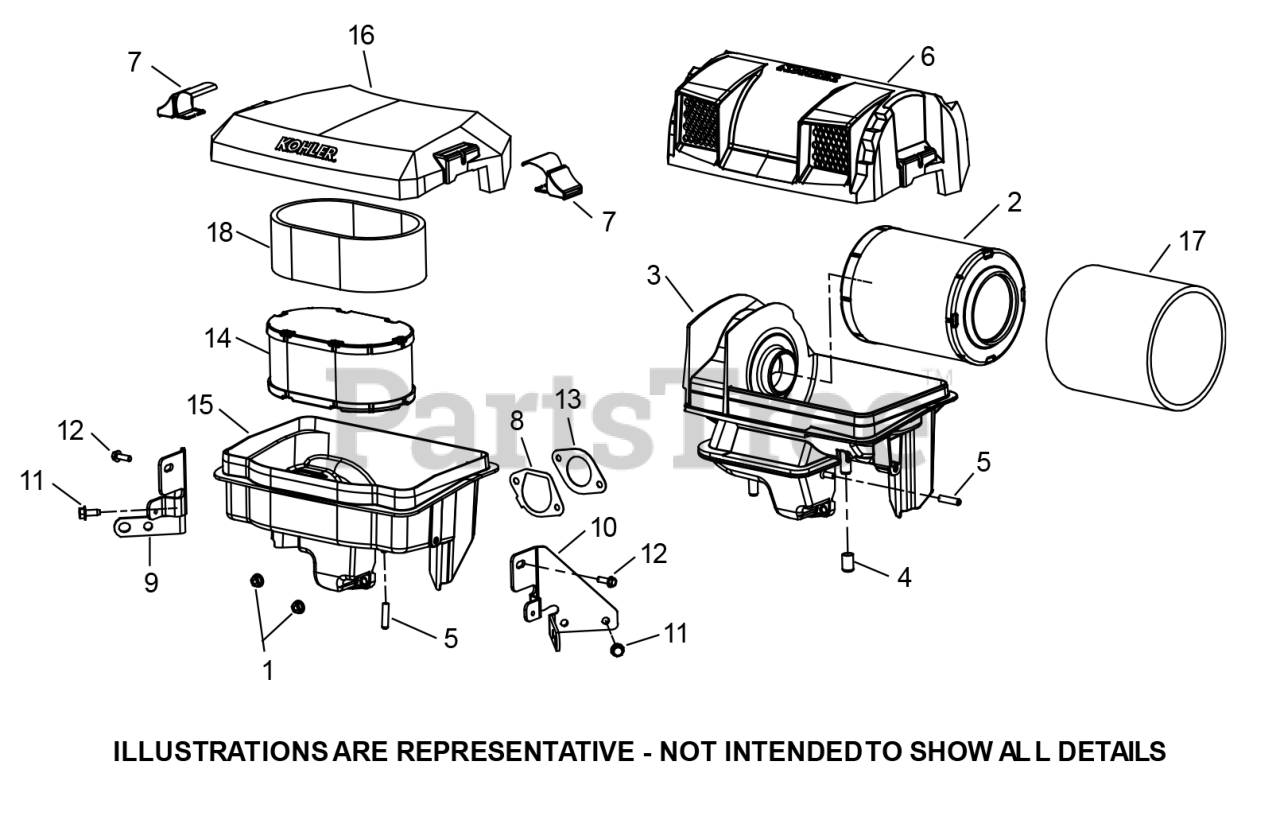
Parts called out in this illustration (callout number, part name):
1	HEX FLANGE NUT
3	BASE ASSEMBLY - AIR CLEANER
6	AIR CLEANER COVER
7	AIR CLEANER COVER
8	GASKET-AIR CLNR BA
9	AIR CLEANER BASE B
10	BRACKET-AIR CLEANER BASE
11	SCREW-THREAD FORMI
13	THROTTLE BODY GASKET
